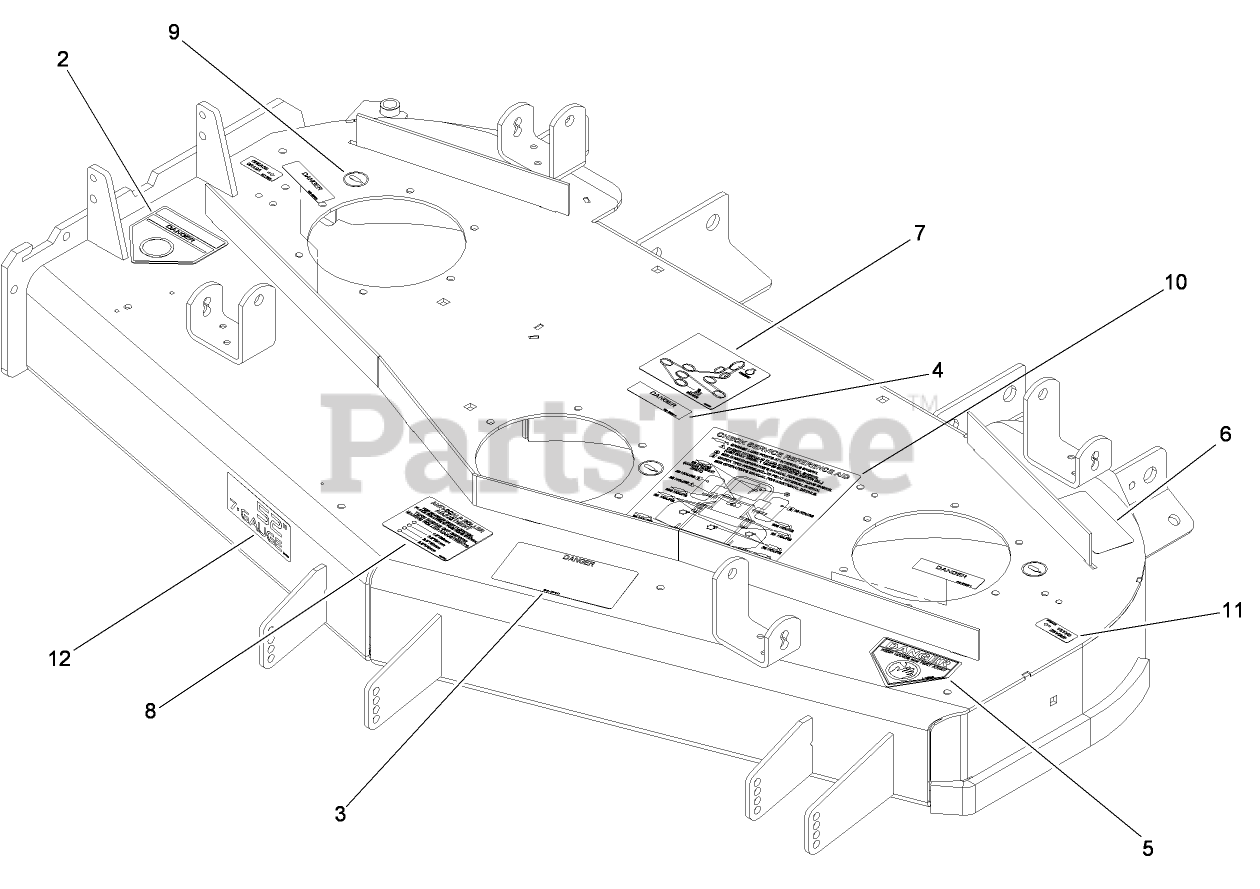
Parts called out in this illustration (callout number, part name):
2	DECAL-DANGER
3	DECAL-DANGER, THROWN OBJECT
4	DECAL-COVER, MISSING
5	DECAL-DANGER
6	DECAL-TORQUE
7	Decal-Routing, Belt
8	DECAL-SCALP, ANTI
9	DECAL-GREASE
10	Decal-Service, Check
11	Decal-Grease
